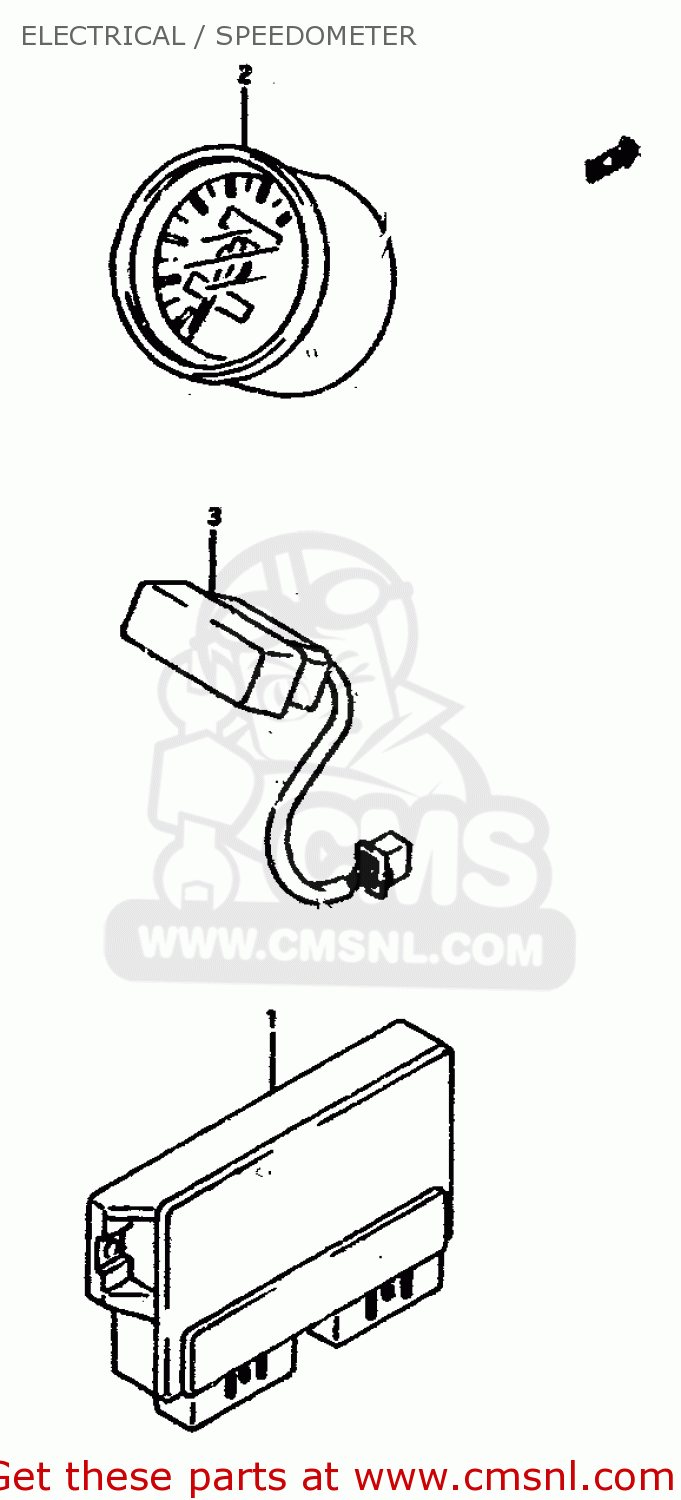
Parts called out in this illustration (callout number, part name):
1	CONTROL UNIT
2	SPEEDOMETER (MILE/KILO)
3	BOX ASSY, PILOT LAMP
